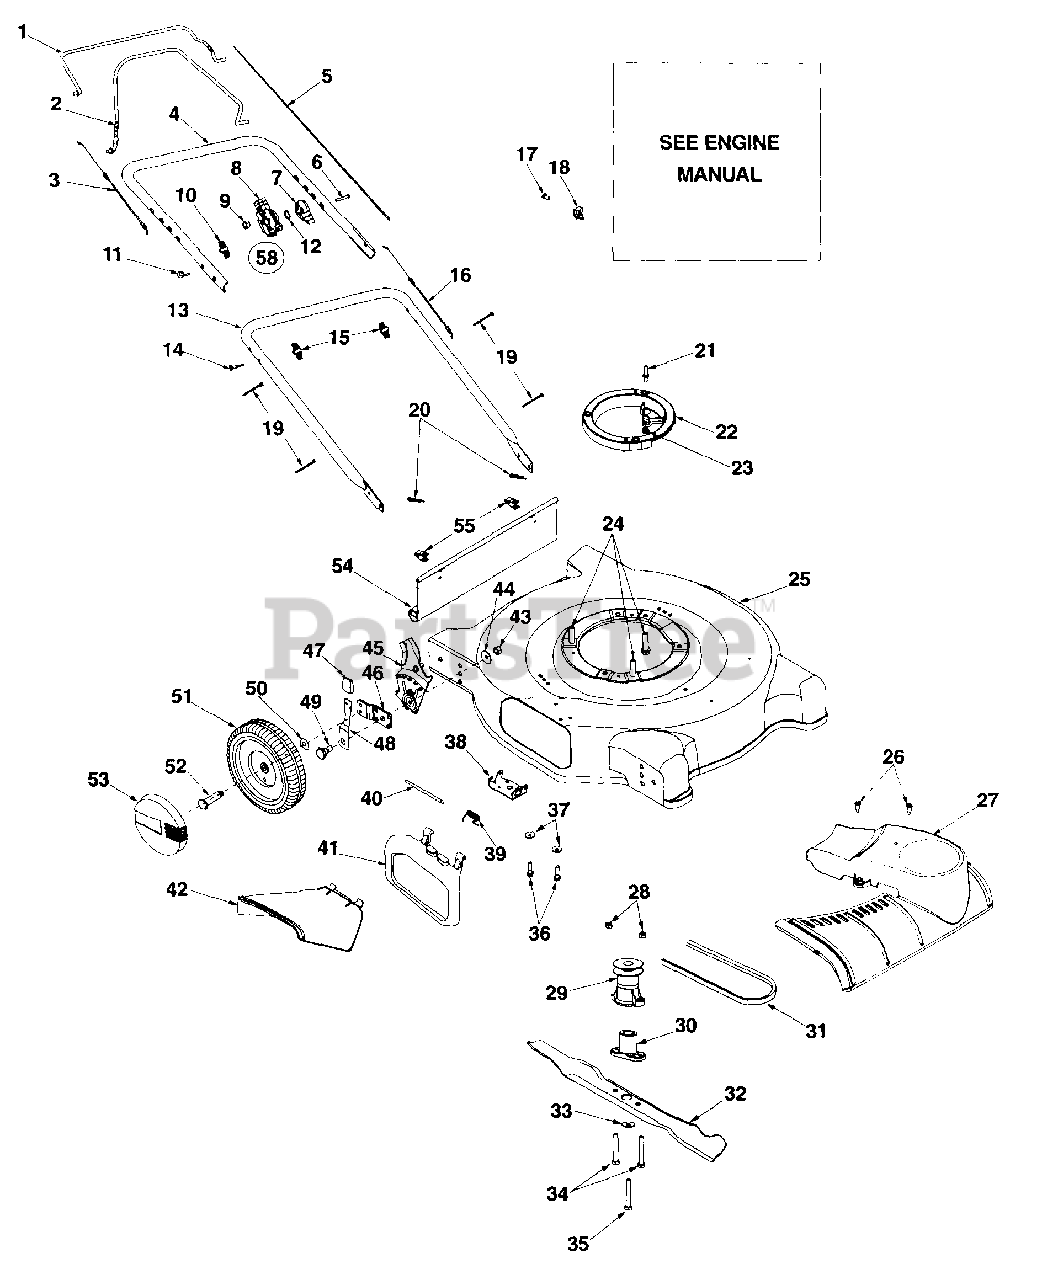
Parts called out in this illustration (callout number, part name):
6	Screw Oval C-Sunk 1/4-20 x 1.81
7	Throttle Lever
8	Throttle Housing
9	Hex Lock Nut 1/4-20
11	Eye Bolt 1/4-20
12	Curved Washer .663 x .980 x .014
14	Carriage Bolt 5/16-18 x 2.0
15	Knob
16	Throttle Cable: 51" (B&S)
17	Hex Screw: T: #10-32 x .625 (B&S)
18	Cable Clamp (B&S)
19	Tie Cable
20	Cotter Pin
21	Pin-Belt Keeper
22	Engine Spacer
23	Hex Nut 1/4-20 Thread
24	Tapp Screw w/Hex Lock Wash
27	Trans Cover - Black w/Logo
28	Hex Lock Nut 1/4-20 Thd.
29	Drive Pulley
30	Blade Adapter Kit
31	V-Belt
32	Blade 22"
33	Bell Washer .396 I.D. x 1.140 O.D. x
34	Hex Screw 1/4-2.0 x 1.50
35	Hex Screw 3/8-24 x 2.50
36	Tapp Screw 1/4-20 x .500
37	Bell Wash .265 x .75 x .062
39	Torsion Spring
40	Hinge Pin
41	Mulch Plug
42	Chute Deflector
43	Hex Nut 3/8-16
44	Bell Washer .39 ID x 1.38 OD
47	Knob
48	Height Lever
49	Shldr Screw .500 Dia x .434
50	Bell Washer .380 x .880 x .062
51	Wheel 8 x 1.75 Disk Bar Gray
52	Shoulder Screw .498 x 1.445
53	Hubcap: Euro: Grey
54	Rear Flap
55	Clip
58	Throttle Comp.
